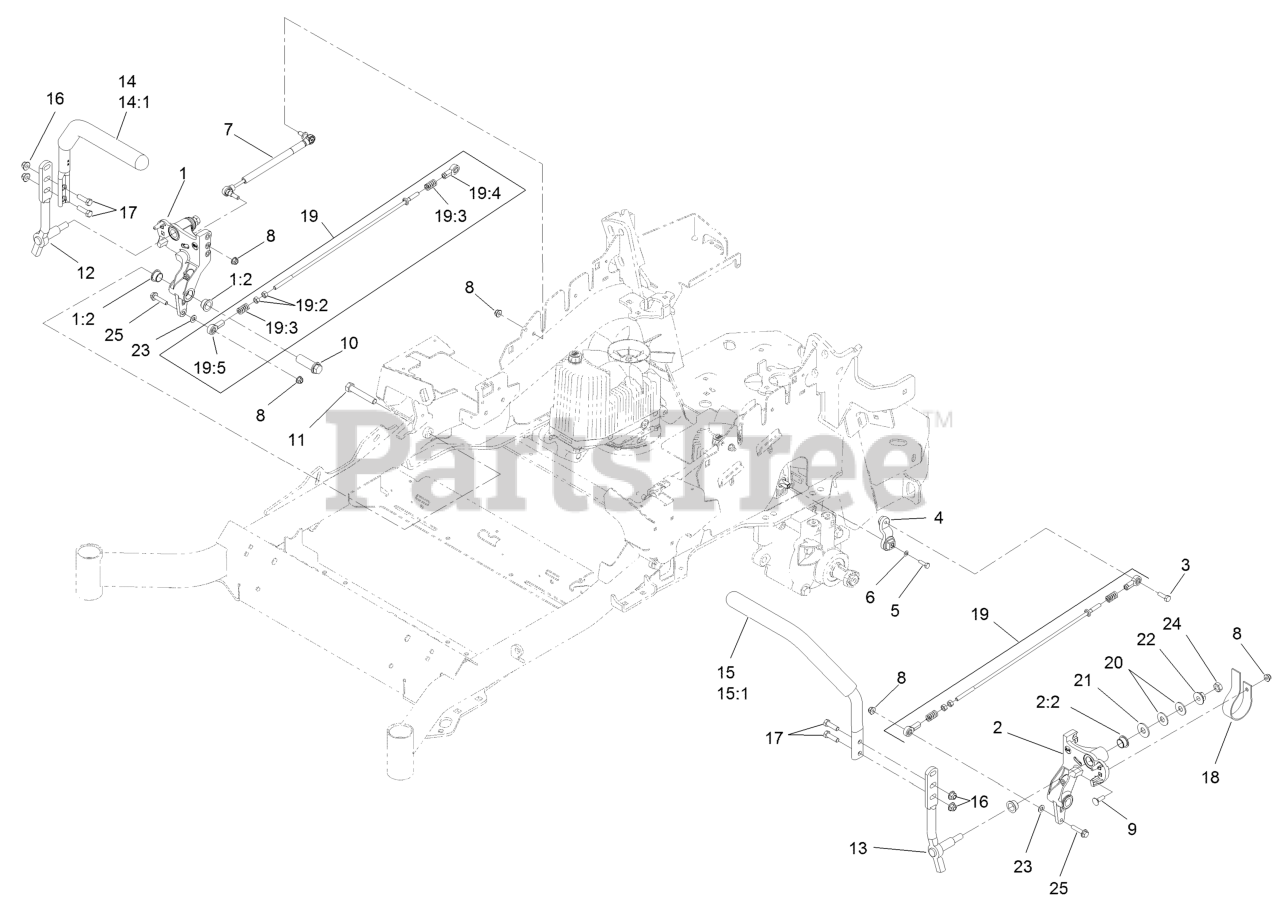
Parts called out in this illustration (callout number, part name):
3	MOUNT-PIVOT, LH
4	MOUNT-PIVOT, RH
5	Screw-HWH 5/16-18 X 3/4 Tf
6	BUSHING-FLANGE
7	BRACKET-MOUNT
8	BRAKE LEVER ASM
8:2	BUSHING-FLANGE
8:3	GRIP-LEVER
9	HANDLE-PIVOT, BRAKE
10	SCREW-HH
11	NUT-HF, NI
12	BUSHING
13	WASHER-FLAT
14	PLATE-MOUNT, BRAKE
15	CALIPER-BRAKE
16	CALIPER-BRAKE, RH
18	ARM-INNER, LH
19	ARM-INNER, RH
20	SHAFT-CROSS
21	WASHER-FLAT
22	SCREW-HHF
23	BRACKET-L
24	LINKAGE-MID
25	YOKE-OFFSET
26	SPRING-COMPRESSION
27	NUT-JAM
28	NUT-HF, NI
29	PIN-CLEVIS
30	WASHER-PLAIN
31	PIN-COTTER, LOCKING
32	FRONT LINKAGE ASM
32:2	END-TIE ROD, RH
32:3	NUT-HJ
33	PIN-COTTER, LOCKING
34	NUT-LOCK
35	REAR LINKAGE ASM
35:3	NUT-JAM
37	BOLT-CARR
38	SCREW-HH
39	NUT-LOCK, NI
40	WHEEL HUB ASM
40:2	STUD-WHEEL
41	LOCKNUT
42	DECAL-COVER
43	SCREW-LOCK, PATCH
